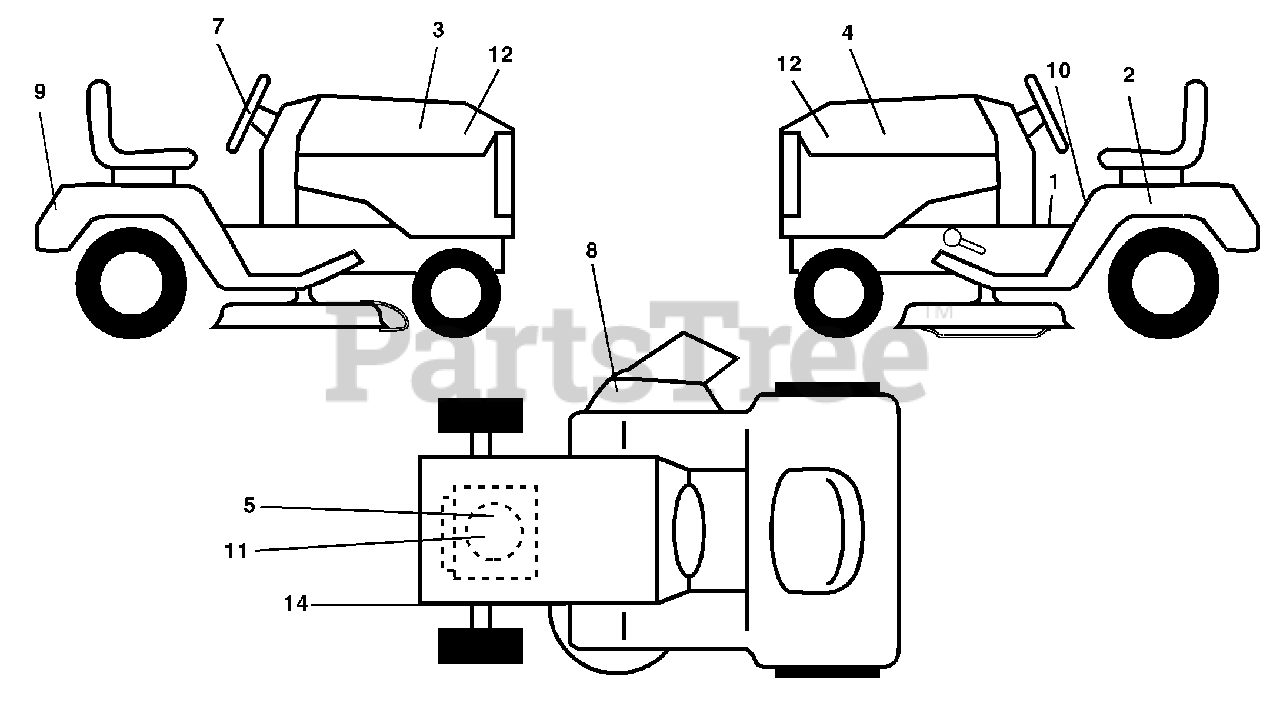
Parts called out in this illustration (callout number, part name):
1	Decal Oper. Step Thru E/F
2	Decal Battery
3	Decal Hood RH
4	Decal Hood LH
5	Decal HP Engine
7	Decal Wheel Steering
8	Decal Warning
9	Decal Fender Husq
10	Decal Fender Danger E/F
11	Decal Engine
12	Decal Hood Logo
14	Decal V-Belt Schematic
